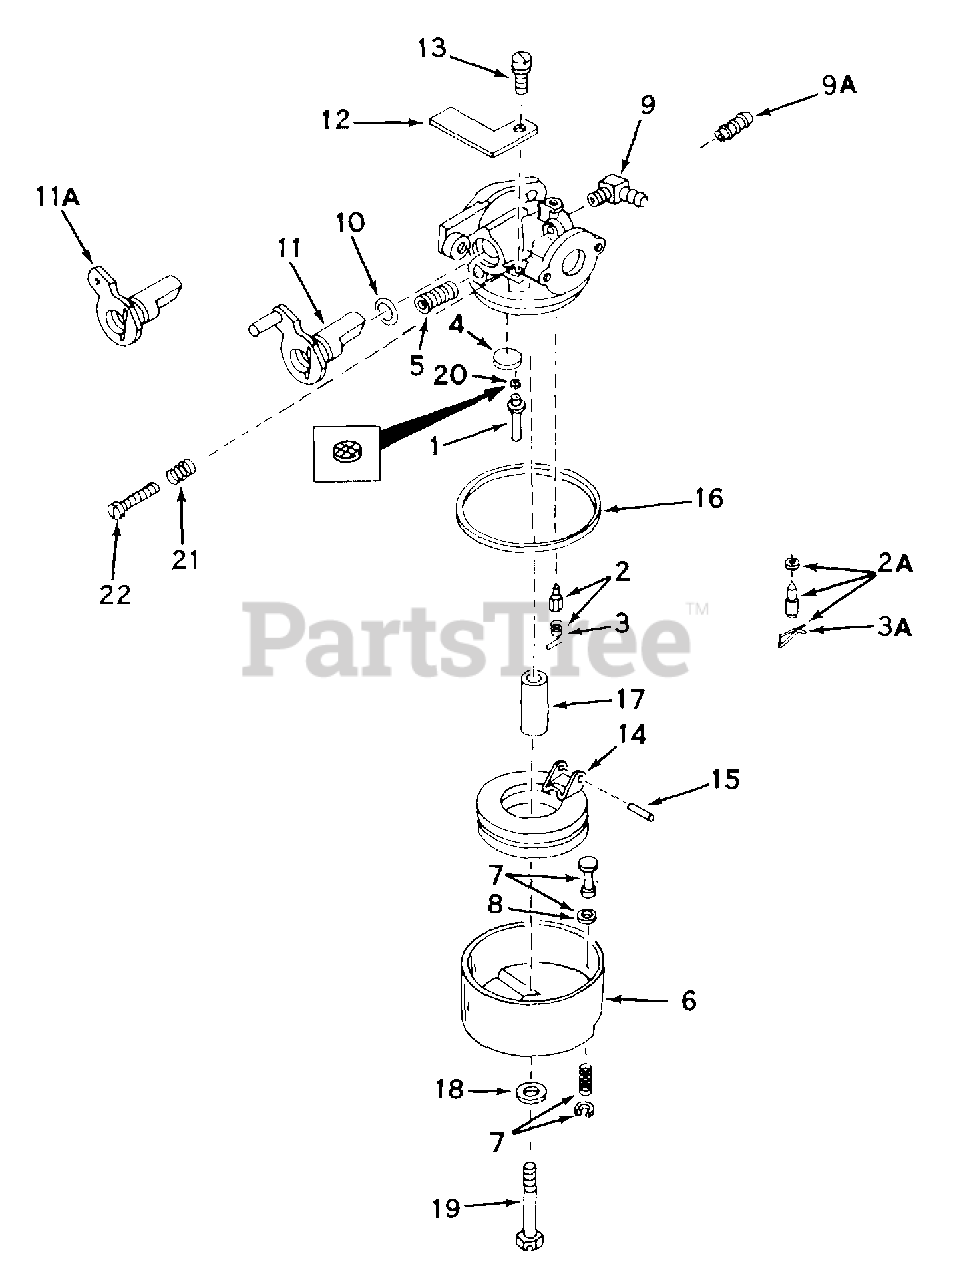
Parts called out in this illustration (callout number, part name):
1	"Tube, Fuel pickup
2	Inlet Needle & Spring Assy.
3	Spring, Inlet needle
4	Plug, Welch
5	Spring, Positioning
6	Bowl, Float
7	Plunger Assy., Drain
8	Gasket, Drain plunger
9	Fitting, Fuel
10	"O" Ring
11	Valve, Control
12	Plate, Retaining
13	Screw, Fit. hd. Sems, 8-32 x 3/8
14	Float, Carburetor
15	Shaft, Float
16	Gasket, Bowl-to-body
17	Spacer, Bowl
18	Washer, Fiber
19	Screw, Hex hd. mach., 10-24 x 1-1/4
